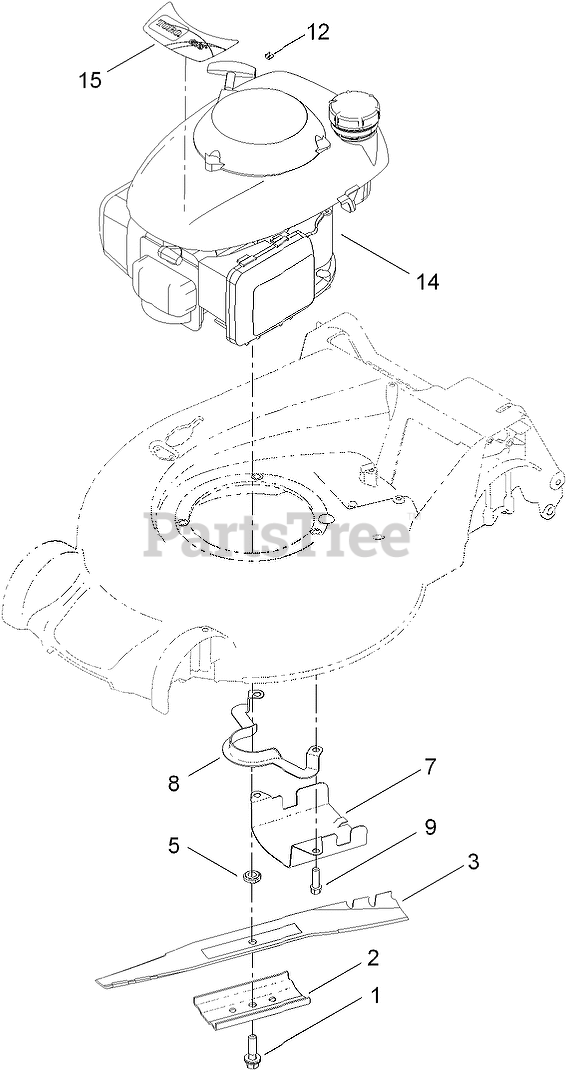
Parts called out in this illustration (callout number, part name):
1	BOLT-BLADE
2	SUPPORT-BLADE
5	Spacer-Driver
7	SHIELD-GRASS
8	GUIDE-BELT
9	SCREW-MOUNT, ENGINE
12	STOP-ROPE
14	ENGINE-HONDA, 880661-GCV160
15	DECAL-ENGINE
